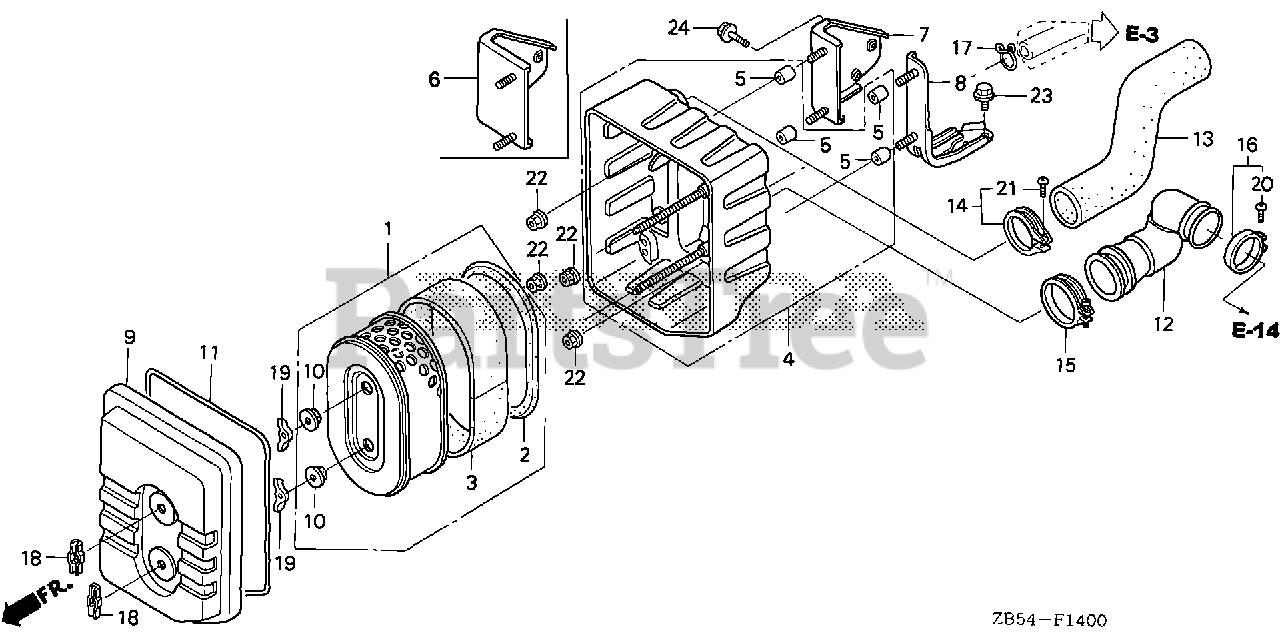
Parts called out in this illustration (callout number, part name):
1	ELEMENT, AIR CLEANER
2	GASKET, AIR CLEANER
3	FILTER (OUTER)
4	HOUSING, AIR CLEANER
5	COLLAR, CONNECTING TUBE SETTING
6	STAY A, AIR CLEANER (6K.V.A)
8	STAY B, AIR CLEANER
9	COVER, AIR CLEANER
10	GROMMET, AIR CLEANER
11	SEAL, AIR CLEANER COVER
12	TUBE, AIR CLEANER CONNECTING
13	TUBE, AIR CLEANER IN.
14	BAND, AIR CLEANER CONNECTING TUBE
15	BAND, AIR CLEANER CONNECTING TUBE
16	BAND, CONNECTING TUBE
17	CLIP, BREATHER TUBE
18	WINGNUT (6MM)
19	WINGNUT, TOOL BOX SETTING
20	SCREW, PAN (4X26)
21	SCREW, PAN (4X20)
22	NUT, FLANGE (6MM)
23	BOLT, FLANGE (6X12) Use up to Engine SN 1543277.
24	BOLT, FLANGE (6X18)
